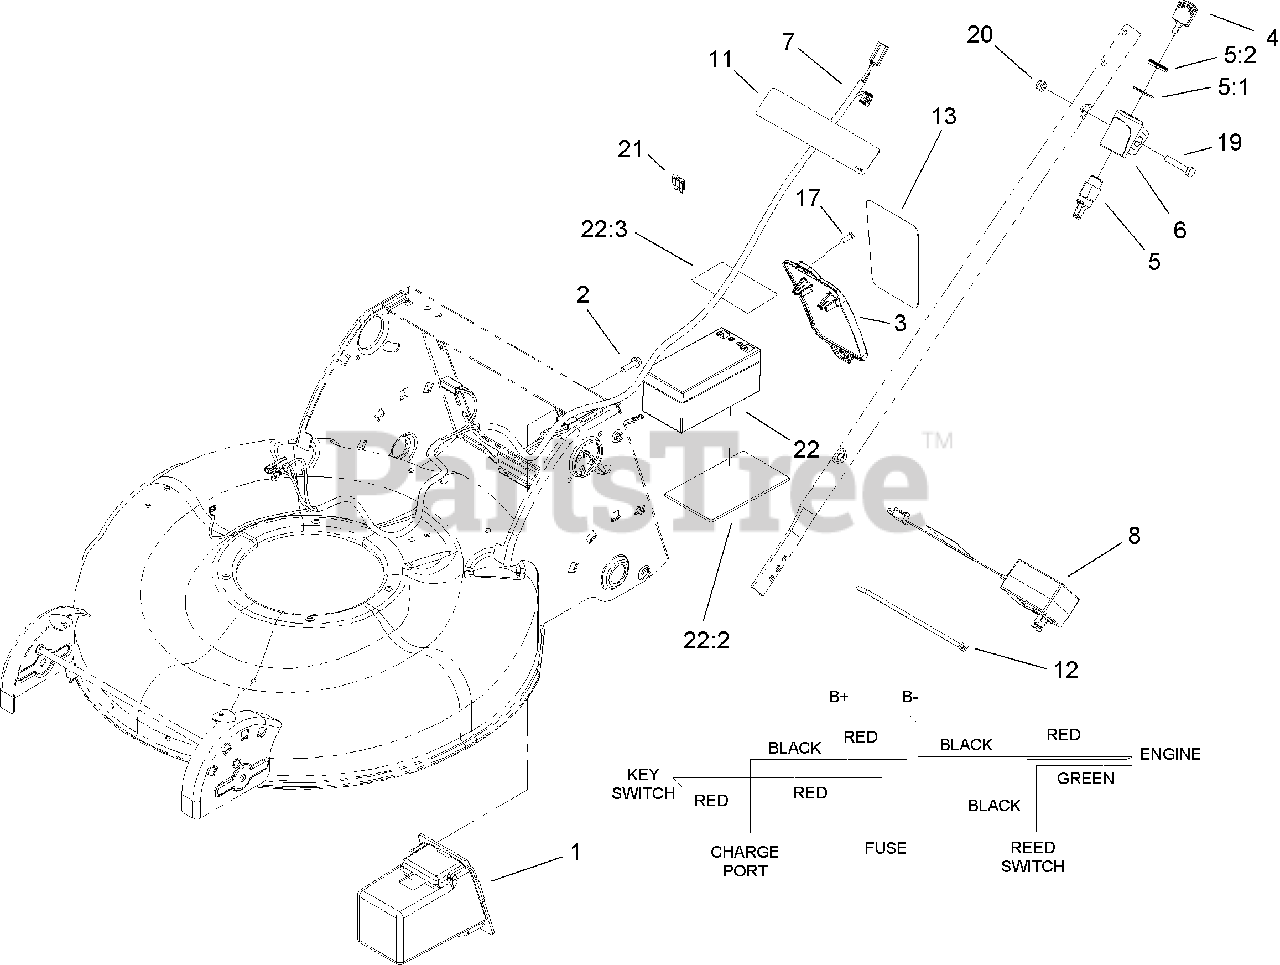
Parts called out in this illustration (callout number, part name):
1	BOX-BATTERY
2	SCREW-HWH
3	COVER-BATTERY
5	SWITCH-STARTER
5:1	WASHER-TOOTH
6	MOUNT-SWITCH
7	HARNESS-WIRE
8	CHARGER-12 VOLT
11	DECAL-HARNESS
12	STRAP-TIE
13	DECAL-INSTRUCTION, BATTERY
17	SCREW-PPH
19	SCREW-HH
20	NUT-LOCK, NI
21	FUSE-40 AMP
22:2	FOAM-BATTERY
22:3	DECAL-BATTERY TERMINAL
